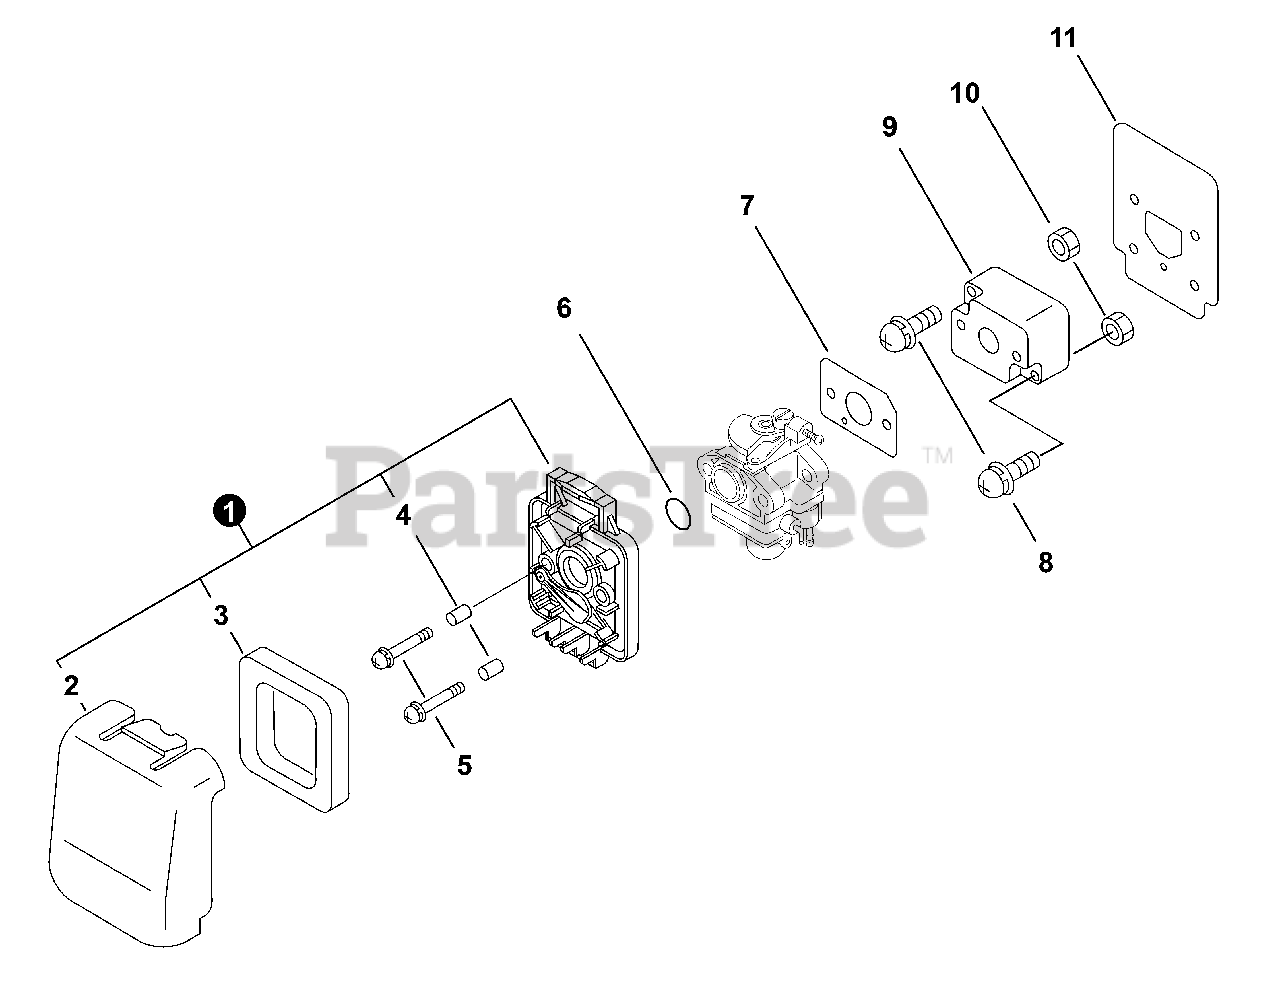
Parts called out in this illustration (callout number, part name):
1	FILTER ASSY, AIR
2	COVER, AIR FILTER
3	FILTER, AIR
4	SLEEVE
5	SCREW 5×64
6	O-RING 15
7	GASKET, CARBURETOR
8	SCREW 5×22
9	INSULATOR, INTAKE
11	GASKET, INTAKE
